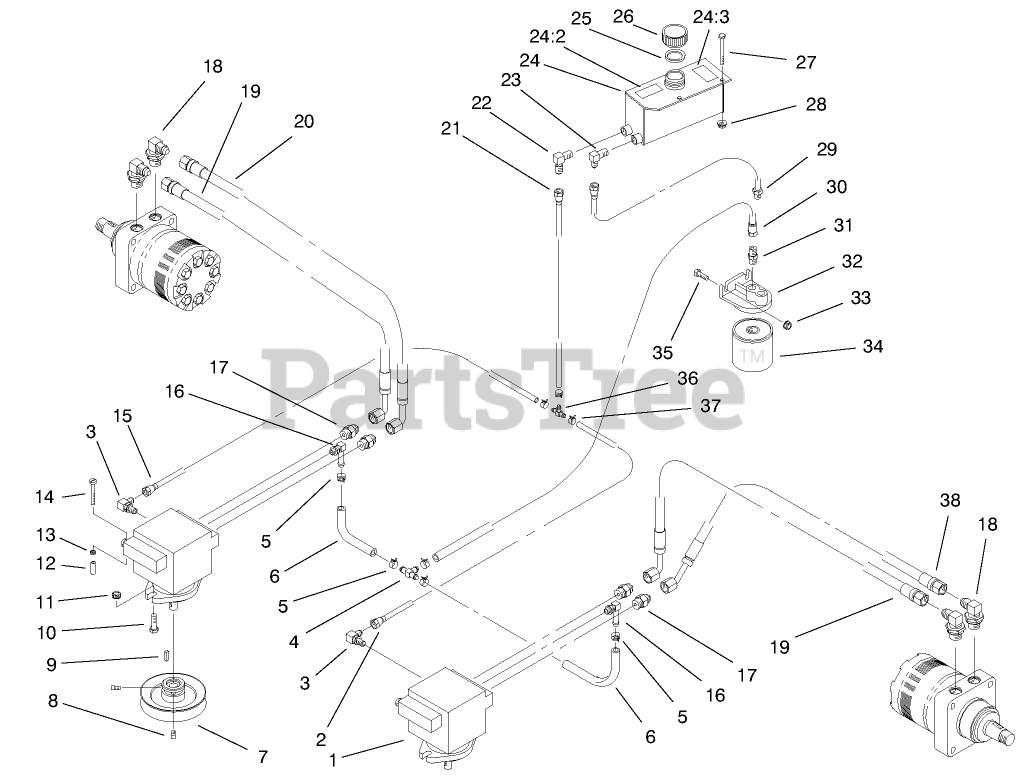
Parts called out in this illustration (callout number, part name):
1	Pump-Hydro
2	Hose-Low Pressure
3	Elbow
4	Fitting
5	Clamp-Hose
6	Hose-Low Pressure
7	Sheave w/Hub
8	SCREW-SET, SQH
9	Key
10	SCREW-HH
11	NUT-HHF, WHIZ
12	Grip
13	NUT-LOCK, NI
14	Screw-PPH
15	Hose-Low Pressure
16	Elbow
17	Adapter
18	Elbow 90
19	Hose
20	Hose
21	Hose
22	Elbow
23	Elbow
24	HYDRAULIC TANK ASM
24:2	DECAL-SURFACE, HOT
24:3	Decal-Hydraulic Tank
25	Gasket
26	Cap
27	SCREW-HH
28	NUT-HF
29	Hose
30	Hose
31	Connector
32	Head-Filter
33	NUT-HF
34	Filter-Hydro
34	Filter-Winter
35	SCREW-HH
36	Fitting
37	Clamp-Hose
38	Hose
